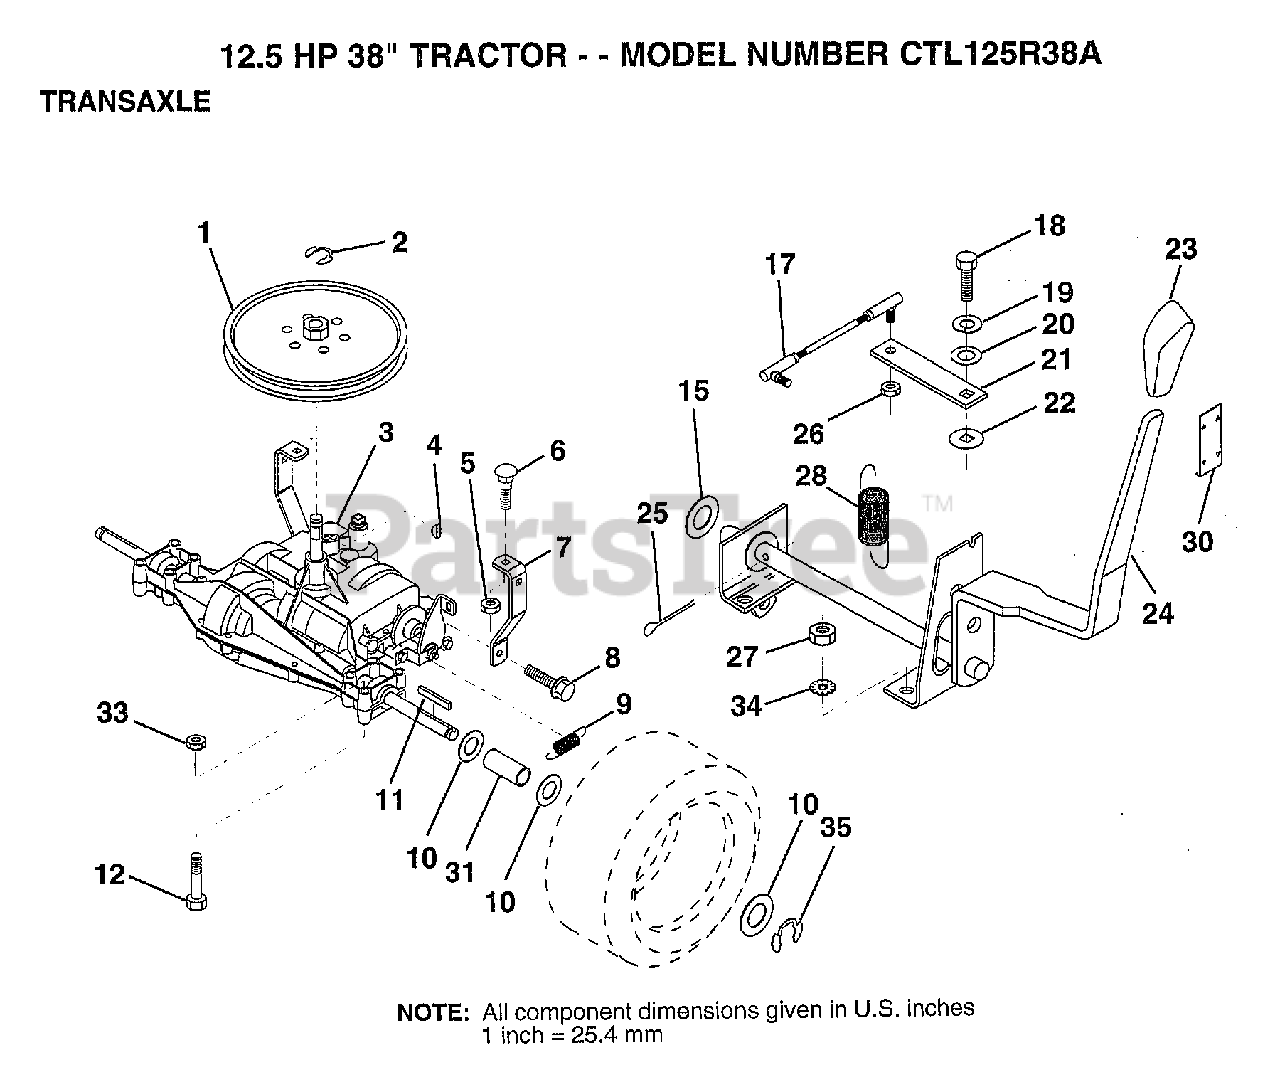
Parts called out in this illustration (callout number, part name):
1	PULLEY
3	TRANSAXLE.6SP.D
6	BOLT
7	"STRAP,TORQUE"
8	SCREW
10	WASHER
11	SQUARE KEY
12	BOLT
17	"LINK,SHIFT"
19	LOCKWASHER
20	WASHER LT
21	"ARM,SHIFT"
22	WASH-SHFT PLT LT
23	"KNOB,SHT CONTROL"
25	PIN COTTER 1/8
26	NUT.LOCK.5/16-24
28	"SPRING,EXT"
30	KNOB RETAINER
31	SPACER
34	LOCKWASHER.5/16.E
35	E-RING LT
